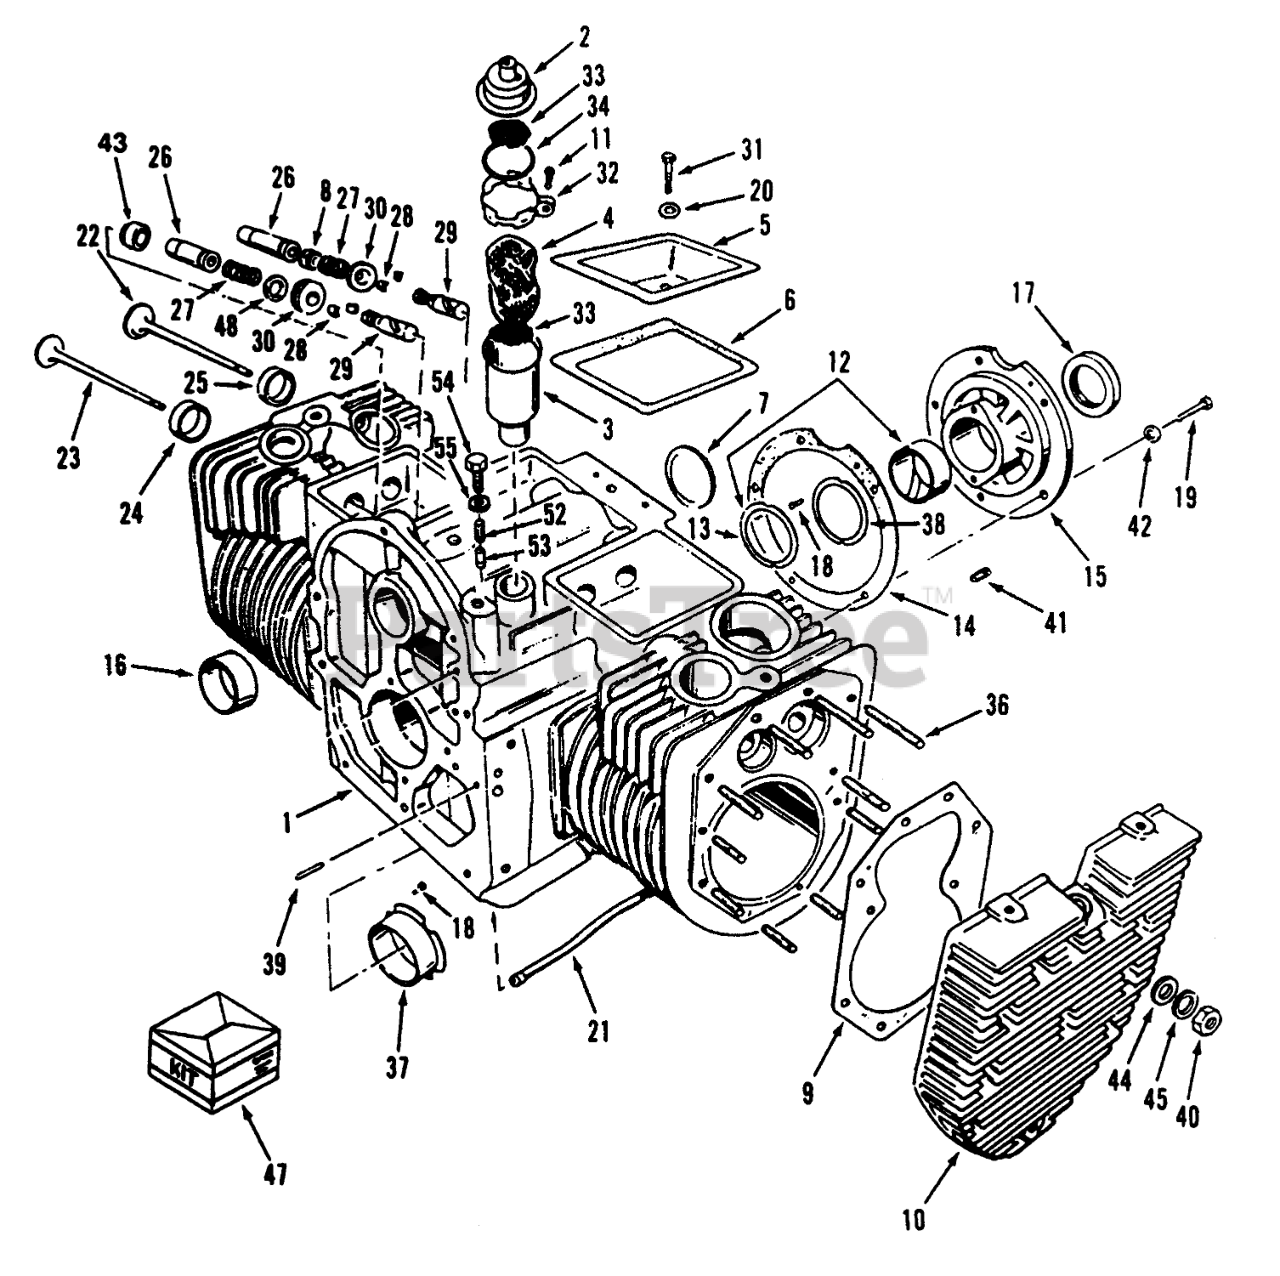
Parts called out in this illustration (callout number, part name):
1	Block-Short 24 HP Spec E (Incl. Ref.# 3, 7, 13-16, 18, 21, 24-26, 30, 36, 38 & 39)
2	BREATHER-CAP AND VALVE
3	TUBE-BREATHER
4	FILTER
5	VALVE COMPARTMENT
6	GASKET-VALVE COVER
8	SEAL-INTAKE VALVE
9	GASKET-CYLINDER HEAD
10	HEAD-CYLINDER
11	SCREW-TAPPING, ROUND HEAD
12	BEARING KIT (STANDARD SLEEVE)
13	WASHER
14	GASKET
15	Plate-Bearing
16	SLEEVE-BEARING
18	PIN-DRIVE
19	HEX HD CAPSCREW
20	WASHER
21	TUBE-OIL, CRANKCASE
22	Intake Valve
23	Exhaust Valve
24	INSERT
25	INSERT-VALVE SEAT
26	GUIDE-VALVE, EXHAUST
27	SPRING
28	LOCK-VALVE SPRING
29	TAPPET
30	ROTOCAP
31	SCREW - CAP HEX HEAD
32	Clamp
33	SCREEN-BREATHER TUBE
34	SEAL - O-RING
36	STUD-CYLINDER HEAD
37	KIT-BEARING, SLEEVE
39	PIN-GEAR COVER
40	NUT-HEX
41	Screw
42	WASHER-FLAT
43	Cap-Exhaust Valve
44	WASHER-FLAT HD, TREATED
45	WASHER-LOCK, COMPRESS
47	KIT-GASKET CARB REM
48	WASHER
